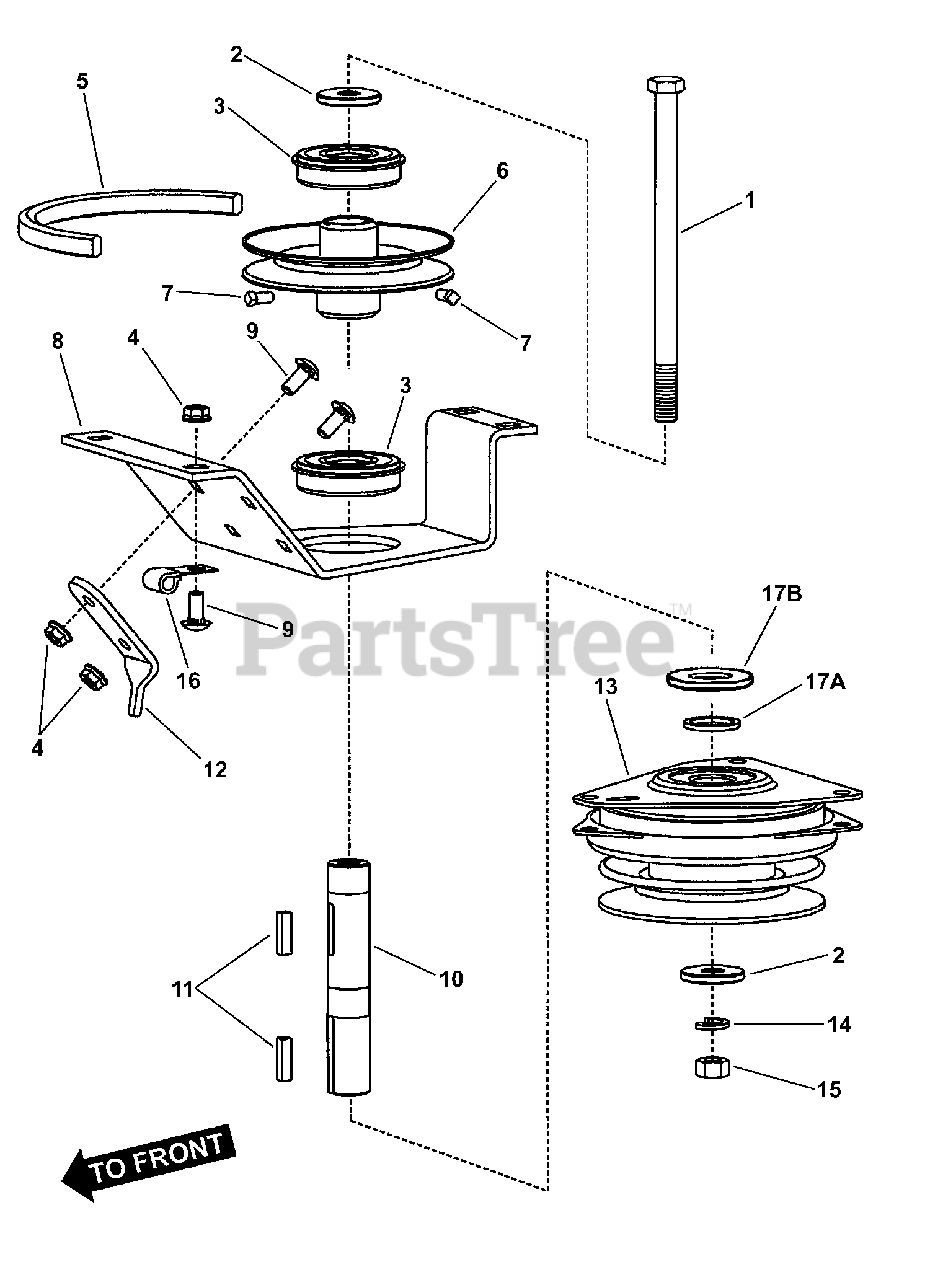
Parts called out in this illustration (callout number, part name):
1	BOLT, 7/16-20 x 8" Hex Head, GR 5
2	WASHER, .468 I.D. x 1.50 O.D. x .188 Flat
3	BEARING, 6305 w/Snap Ring
4	NUT, 5/16-18 Hex Flange Lock, GR 5
5	V-BELT, 5L Sect. Cog, 50.170" effective length
6	PULLEY, Jackshaft
7	SCREW, 1/4-20 x 1/2" Set w/Patch
8	SUPPORT, Jackshaft- TG 2000
9	BOLT, 5/16-18 x 3/4" Short Neck Carriage, GR 5
10	JACKSHAFT, 5.525" long
11	KEY 1/4" Square x 1"
12	BRACKET, Anti-Rotation
13	CLUTCH, Electric Ogura MA-GT-SN11S (33" units)
14	WASHER, 7/16" Split Lock
15	NUT, 7/16-20 Hex, GR 5 or B
16	WIRE CLIP 7/16", Vinyl Covered
17A	SPACER, Jackshaft
17B	SPACER, Clutch (Ogura)
